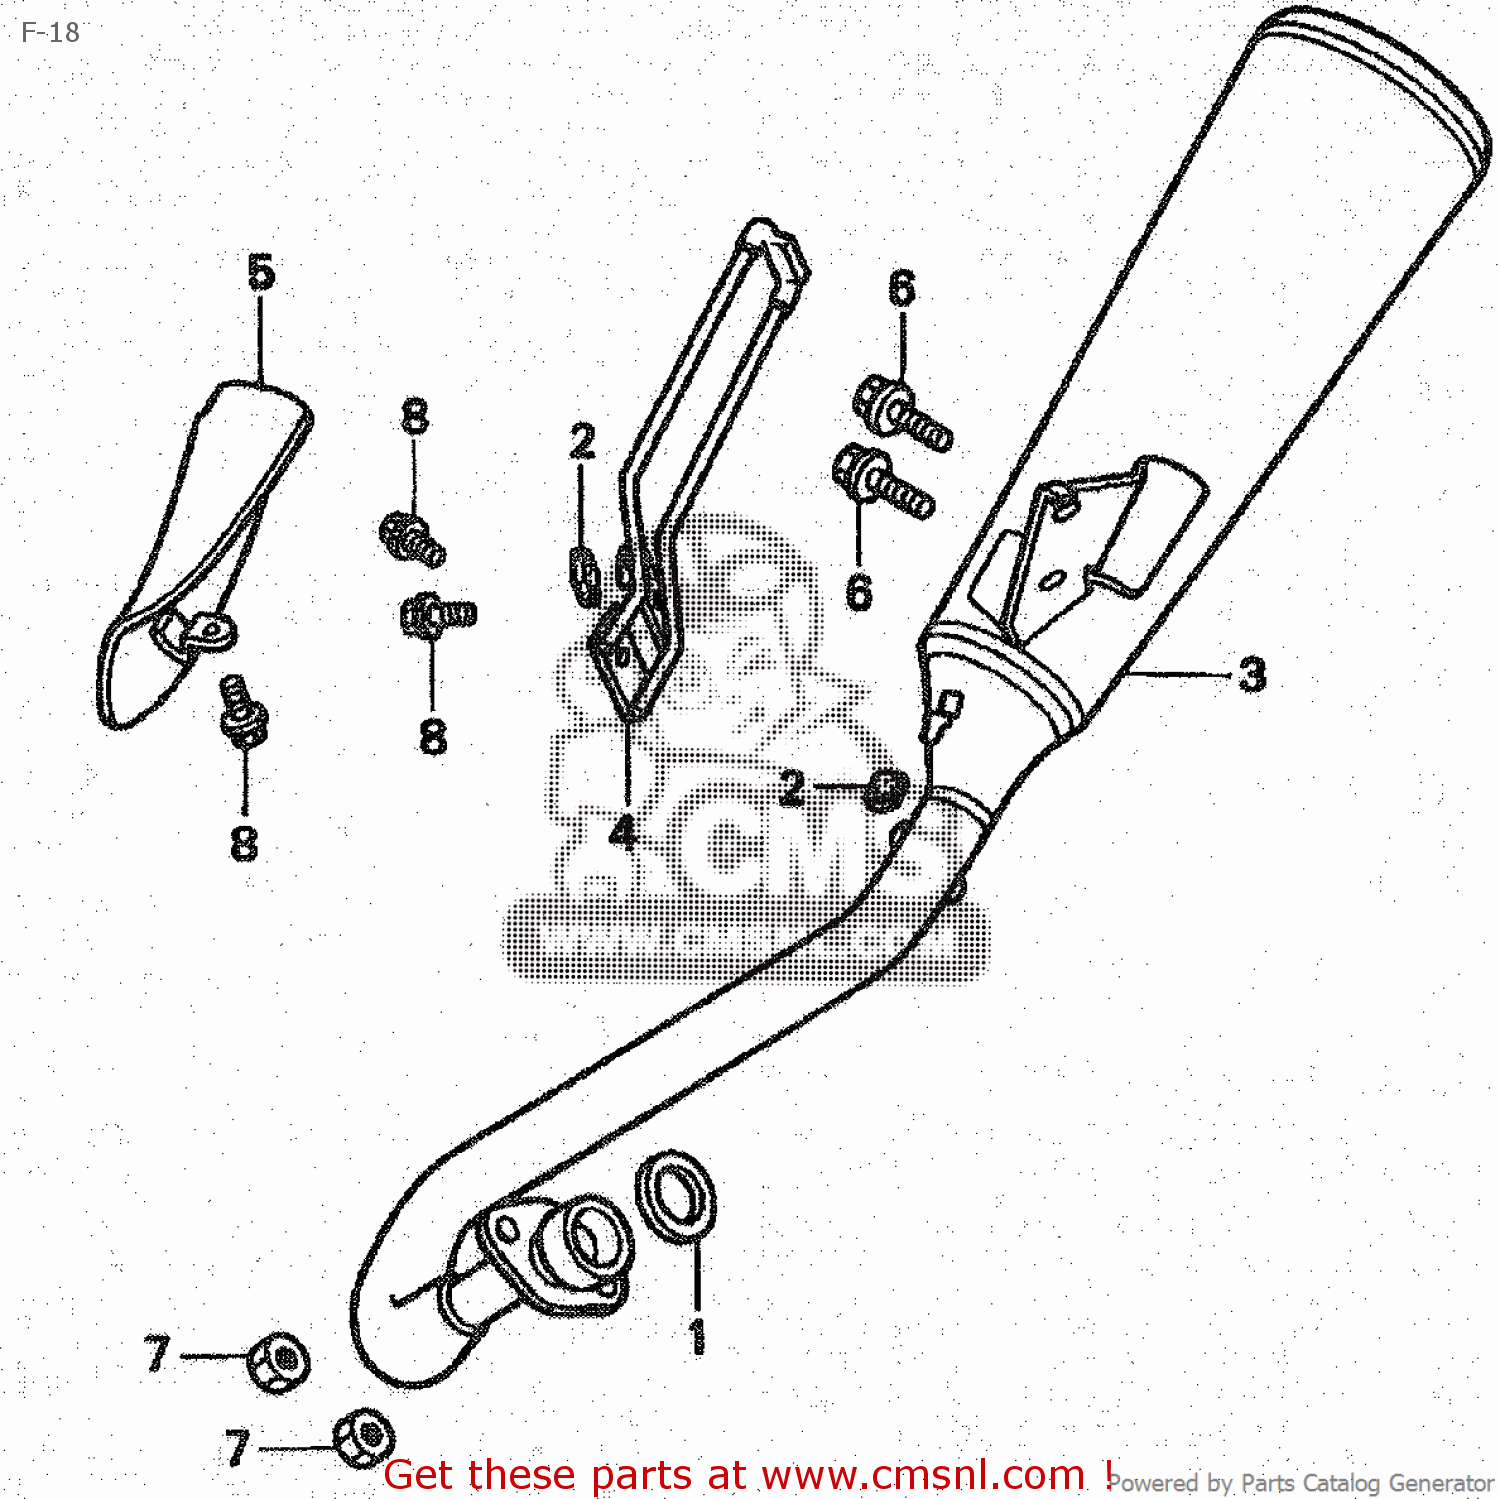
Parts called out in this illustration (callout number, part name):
1	GASKET,EX.PIPE (NAS)
2	RUB.,PROTR.PKG. (NAS)
3	MUFFLER COMP,EXH
4	GUARD,MUFFLER (JDM)
5	PROTECTOR MUFFLER
6	BOLT SPECIAL 8X16
7	NUT,HEX 6MM
8	BOLT,FLANGE,6X8
